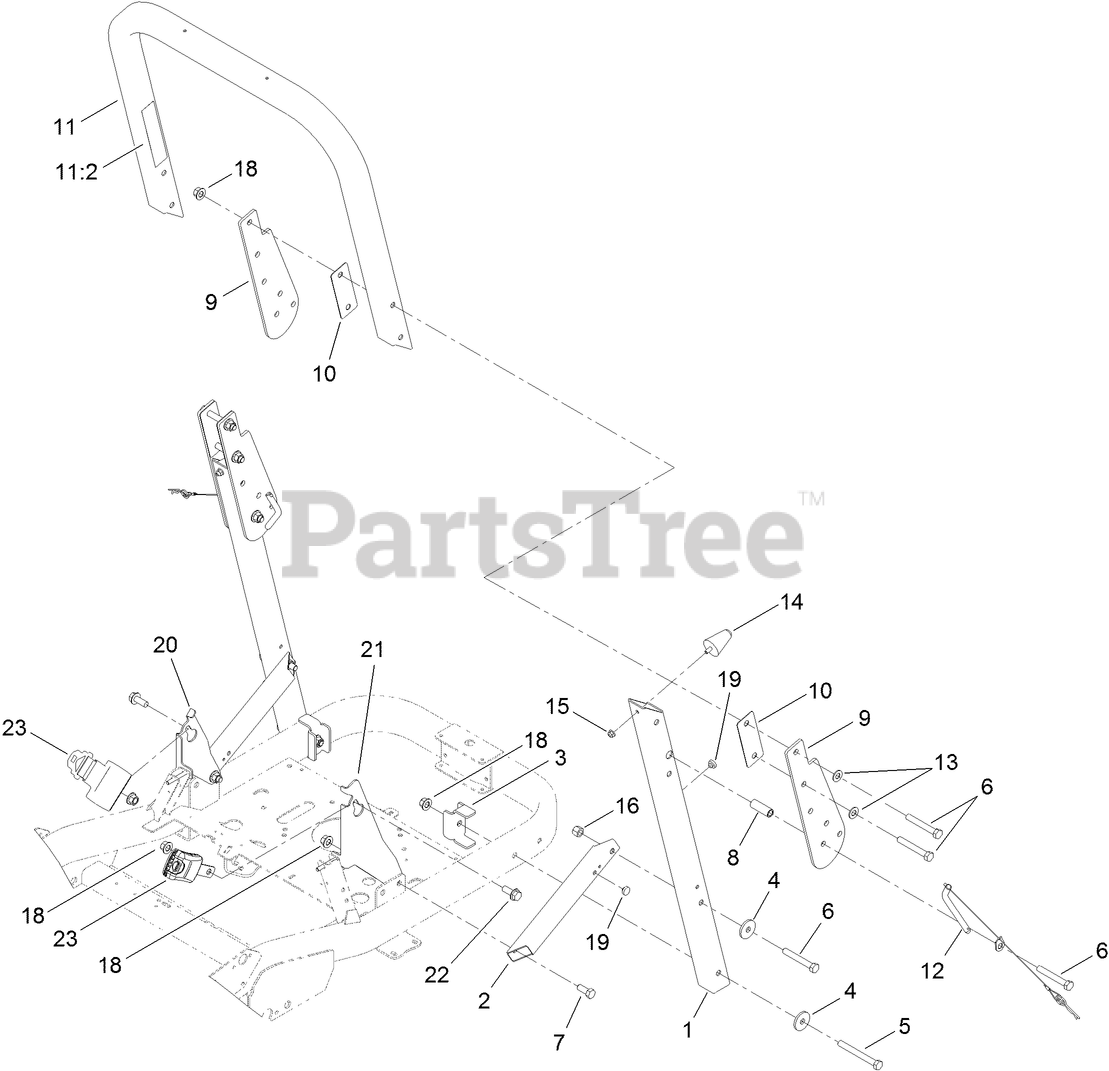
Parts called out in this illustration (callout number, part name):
1	TUBE-ROPS, LOWER
2	TUBE-SUPPORT, ROPS
3	BRACKET-REINFORCING
4	WASHER-THRUST
5	SCREW-HH
6	SCREW-HH
7	SCREW-HH
8	SPACER
9	BRACKET-PIVOT, ROPS
10	SPACER-ROPS
11	UPPER ROPS ASM
11:2	DECAL-WARNING
12	PIN-ROPS
13	WASHER-FLAT
14	BUMPER-RUBBER
15	NUT-HF, NI
16	NUT-HEX
18	NUT-LOCK
19	BUMPER
20	BRACKET-BELT, SEAT
21	BRACKET-BELT, SEAT
22	SCREW-HHF
23	SEAT BELT KIT
